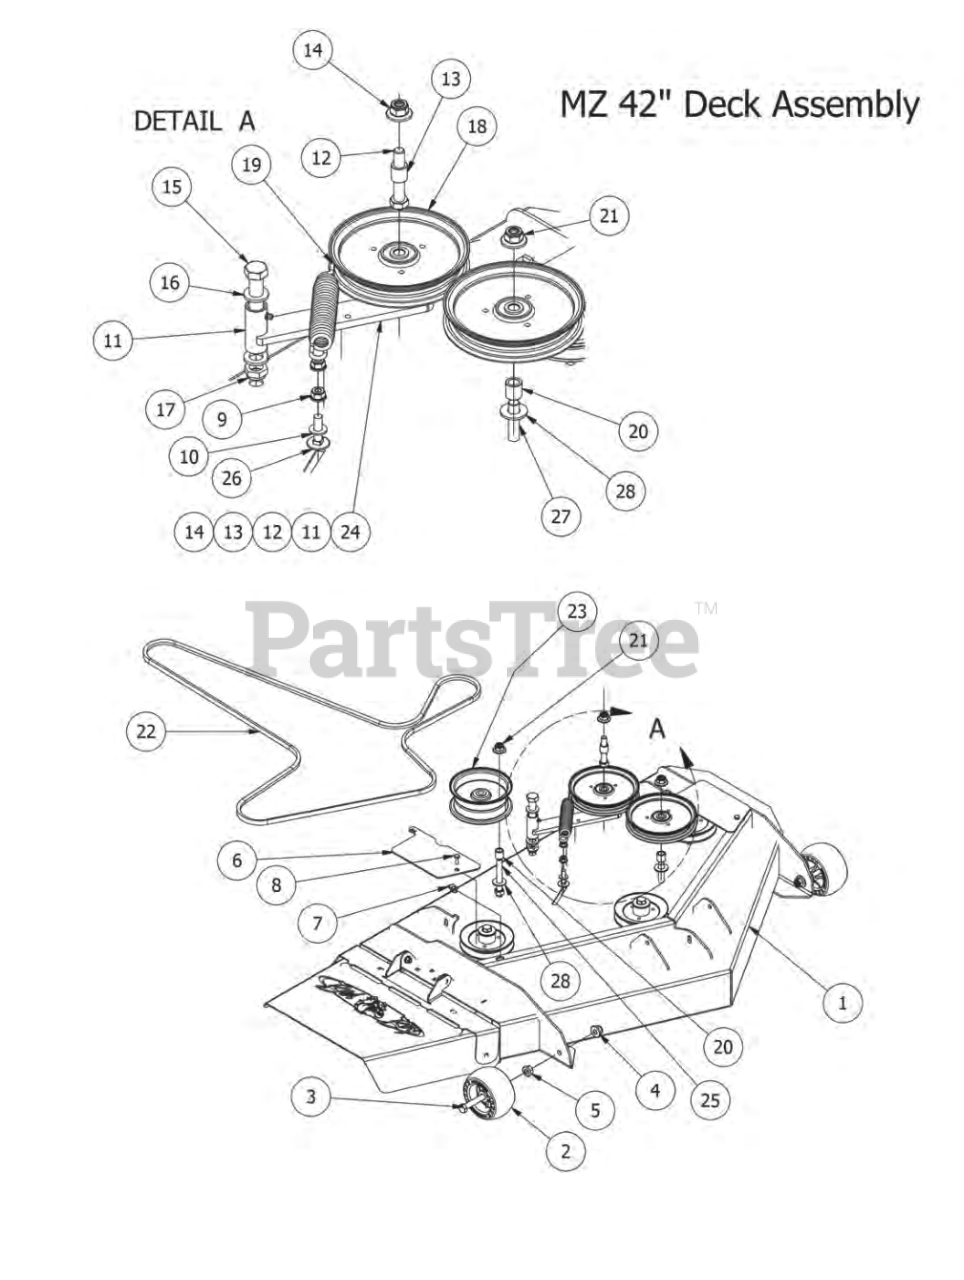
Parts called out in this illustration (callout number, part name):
1	Mz 42 Deck
2	Deck Wheel
3	1/2 x 3 1/2 Flange Bolt Grade 8
4	1/2-13 Nylon Flange Nut-Orange
5	1/2-13 Hex Flange (GR.G) ZC
6	MZ42 Pulley Cover
7	1/4-20 Cage Nut
8	1/4" x 3/4" Hex Bolt
9	3/8" Nylock Flange Nut
10	3/8" Flat Washer
11	Deck Idler
12	1/2" x 2 3/4" Hex Bolt
13	3/4 OD x 1/2 ID x 3\4 Length
14	1/2-13 Nylon Flange Nut-Orange
15	5/8" x 4" Hex Bolt
16	.635 ID Plastic Washer
17	5/8-11 Nylon Insert Jam Half Nut
18	5-3/4 Idler Pulley
19	Deck Idler Spring MZ
20	3/4 OD x 1/2 ID x 3\4 Length
21	1/2-13 Nylon Flange Nut-Orange
22	42" Deck Belt-B120
23	5 3/4" Deck Idler Pulley
24	Parts 11,12,13,14,18 make up the deck idler assembly
25	1/2-13 x 3 1/2 GR 5 Hex Bolt
26	3/8 x 1-1/2 Carriage Bolt
27	1/2-13 x GR 5 Hex Bolt Zinc
28	1/2" Washer (Grade 8)
